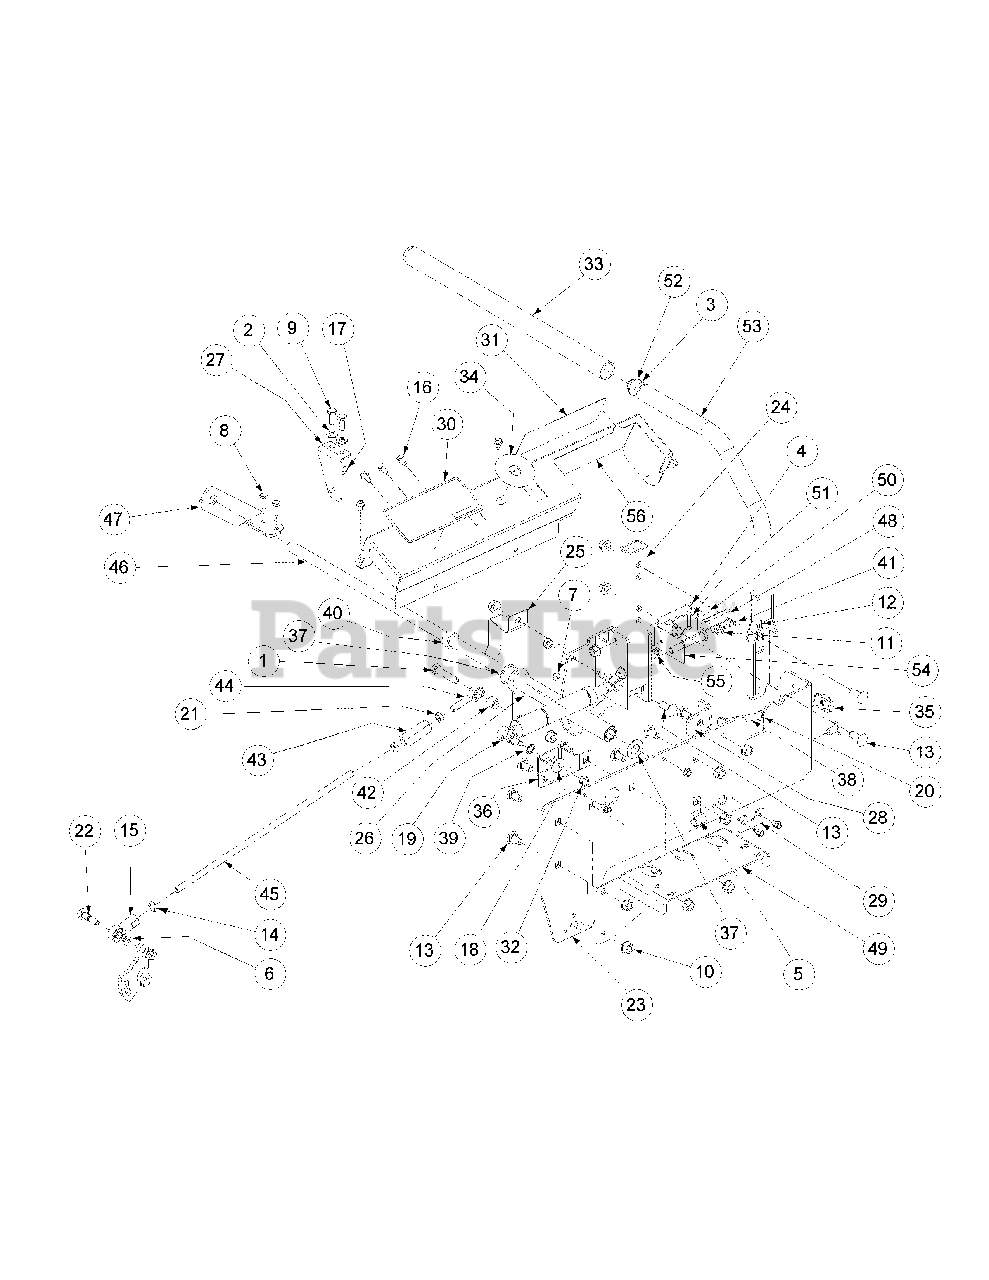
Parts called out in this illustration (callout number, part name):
1	Capscrew, 3/8-16 x 1-3/4
2	Flat Washer, 5/16
3	Lock Washer, Ignition Switch
4	HHCS, 3/8-16, 2.5
5	Clip, Heat Shield
6	5/16, Lock Washer
7	Grease Fitting, 90°, 1/4-20
8	Screw, TT, 1/4-20, 0.75, Hex Index Washer
9	Hex, Cap Screw, 5/16-18 x 3/4
10	Hex Nut, 3/8-16, Lock Flange
11	Flat Washer, 1/4"
12	Split Conduit, 1/4 Poly
13	Carriage Bolt, 3/8-16 x .75
14	Hex Jam Nut, 3/8-24
15	B/Joint, 3/8-24, Right Hand Female
16	Screw, TT, 1/4-20, 0.5, Hex Index Washer
17	Nut, Lock, HexFlange, 5/16-18
18	Belle Washer, .325 x .930 x .045
19	Cylinder Return to Neutral Kit
20	Nut, 3/8-16, Jam
21	Nut, 3/8-24, Jam, LH Third
22	Screw, Shoulder Control Rod
23	Control Panel Mount, RH
24	Mounting Handle
25	Lever, Safety Switch
26	Hub Assy, Control RH Bearing
27	Switch Mounting Bracket, Lapbar
29	Holder Shaft, Park Brake
30	Decal , Right Hand Console
31	Decal Right Hand Control
32	Nut, Hex, Center Lock, M8
33	Grip, 1.0
34	Label, Ingnition, 2.5 Diameter
35	U-Nut, 3/8-16, .75
36	Bracket Assembly, Mount Dampener
37	Flat Washer, 5/8 Nylon
38	HHCS, 3/8-16, 3.00
39	External Tooth Washer, 3/8
40	Shaft Collar
41	Shoulder Bolt, 1/4x1/4
42	Spacer, .385ID x .625 OD x 50 Lg
43	Turnbuckle
44	B/Joint, 3/8-24, LH Male
45	Rod Connector 3/8 OD x 14.125
46	Shaft Mounting Belle Crank
47	Lapbar Shaft Support
48	Grip, Speed Lever
49	Valve Control Mounting Plate
50	Plunger, 1/4-20 x 3/4
51	Speed Control Adjuster Assembly, RH
52	Lapbar Switch, On/Off
53	Lapbar Handle Weldment, RH
54	Speed Control Detent Plate
55	Nut, 10-24, w/Star Washer
56	Control Panel, RH
